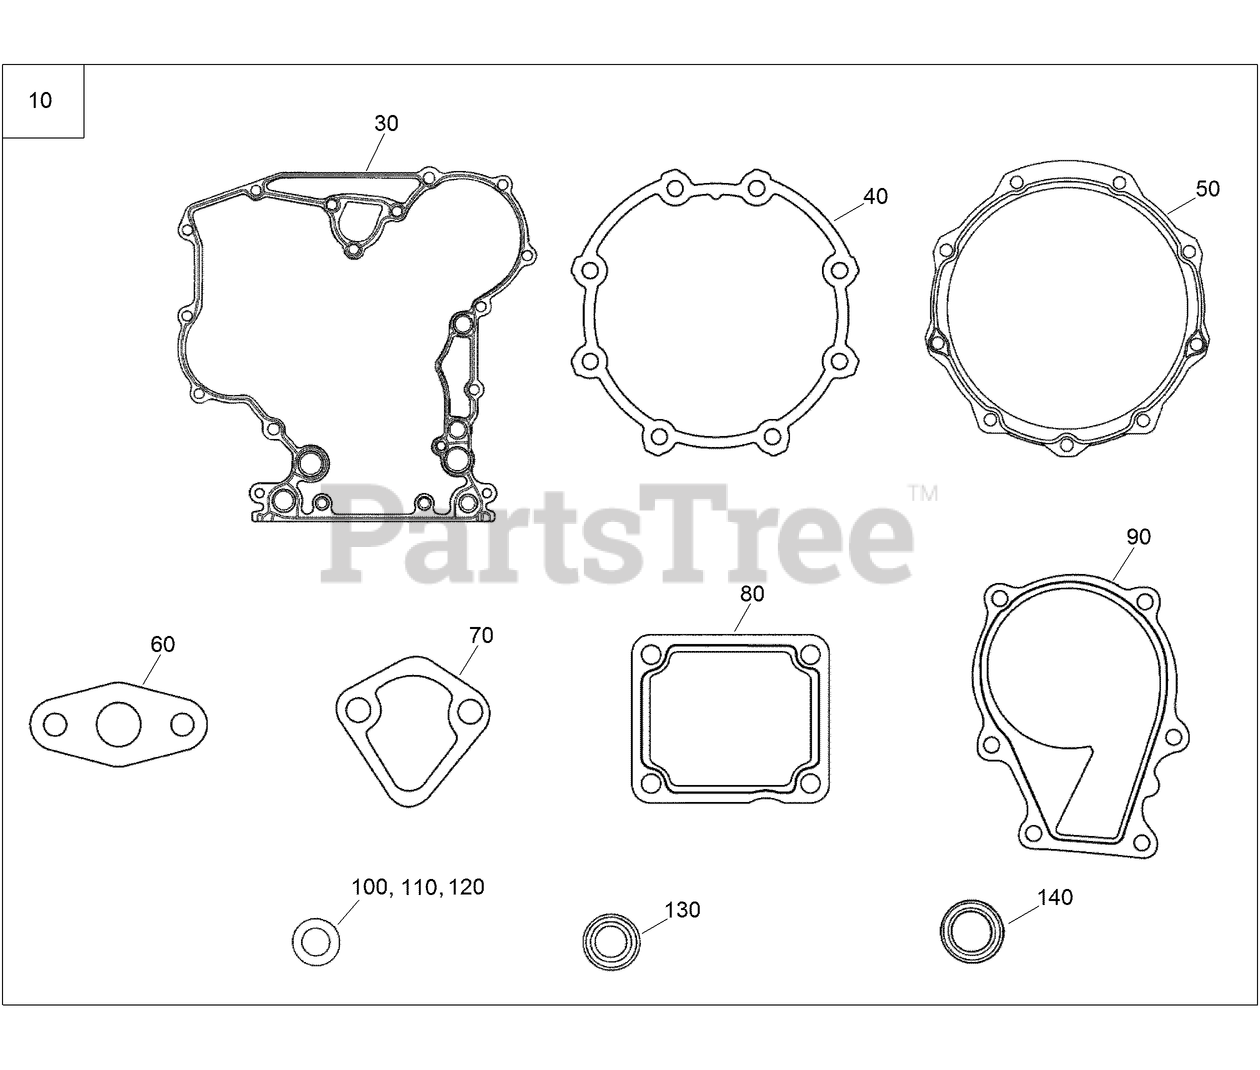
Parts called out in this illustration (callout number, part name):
10	LOWER GASKET KIT
30	GASKET-CASE, GEAR
40	GASKET-CASE, BEARING
50	GASKET-COVER, CASE
60	GASKET
70	GASKET-PUMP, FUEL
80	GASKET
90	GASKET-PUMP, WATER
100	GASKET
110	GASKET
120	GASKET-PAN, OIL
130	SEAL-OIL
140	SEAL-OIL
